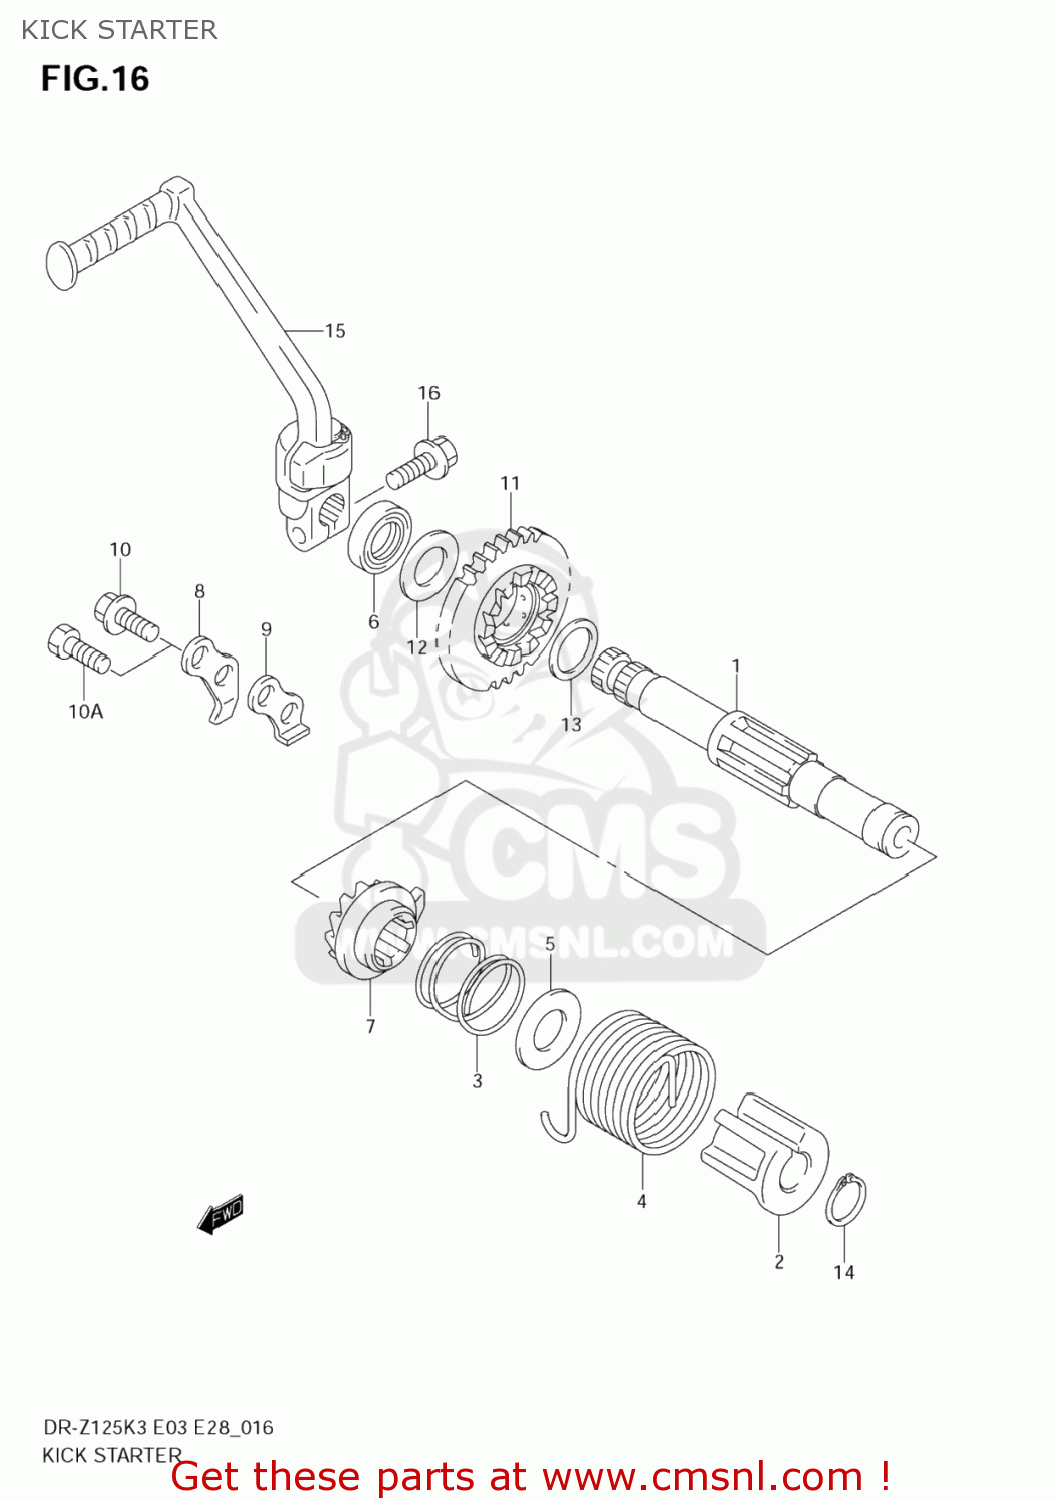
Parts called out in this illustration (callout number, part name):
1	SHAFT,KICK STARTER(NT:31)
2	GUIDE,KICK STARTER SFT SPRING
3	SPRING
4	SPRING
5	WASHER
6	SEAL,OIL(16X24X5)
7	STARTER,KICK
8	GUIDE,KICK STARTER
9	STOPPER,KICK STARTER
10	BOLT
10A	BOLT(8X20)
11	GEAR,KICK STARTER DRIIVE
12	WASHER(16X30X1)
13	SHIM(20X26X1)
14	CIRCLIP,17MM
15	LEVER ASSY,KICK STARTER
16	BOLT
